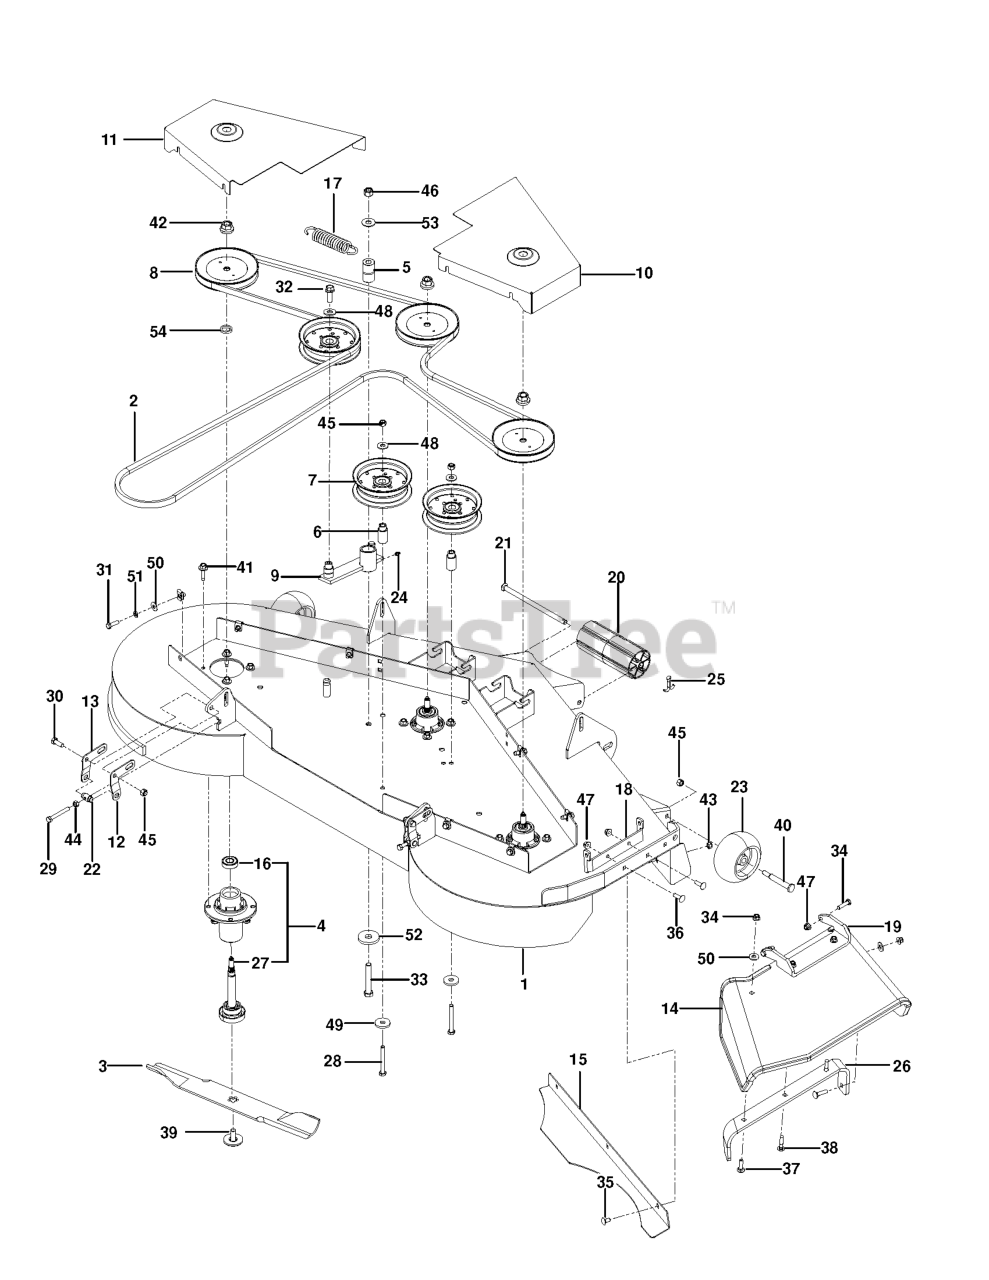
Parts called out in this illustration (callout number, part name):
1	DECK SVC MZT 61 W/DECALS ORG
2	BELT, DECK
3	BLADE, 21"
4	MANDREL ASM, CAST IRON
5	PIVOT BUSHING
6	IDLER BUSHING
7	PULLEY, IDLER
10	BELT SHIELD, RH ORANGE
11	BELT.SHIELD.LH.ORANGE
12	PITCH, ADJUST, RT
13	PITCH, ADJUST, LT
14	CHUTE, RUBBER DISCHARGE 52/61"
15	CONFINEMENT PLATE 61
16	BEARING, BALL
18	BRACKET.M-ZT.CHUTE(ORG)
19	PIVOT BRACKET - CHUTE
20	NOSE ROLLER 48"
21	TRUNION, PITCH
21	ROD.ROLLER.NOSE.NARROW.48"
22	GAUGE WHEEL
23	GAUGE WHEEL
24	ZERK
25	RP_COTTER PIN 1/8 X 3/4
26	BRKT, REINF - CHUTE 52/61"
27	SHAFT ASM MANDREL
28	HCS 3/8C X 3
29	HCS 5/16-18 X 2 1/2 TPBLT
30	HCS 3/8-16X1.GRD.5.ZD
31	HCS 5/16C X 3/4
32	4CS 3/8C X 1 SERRATED HEAD
33	HCS 1/2C X 3 1/4
34	HCS 5/16C X 1 1/4
35	CARRIAGE BOLT 5/16C X 5/8"
36	RHSSNB 5/16C X 1.0
37	BOLT, CARRIAGE 5/16X1-1/4
38	RHSNB 5/16-18 X 1-1/2 GR 5 ZD
39	BOLT.WASHER.ASM.7/16-2
40	SHOULDER BOLT 1/2X2-5/8 ZD SPE
41	WASHER HEAD SCREW
42	LOCKNUT - 9/16
43	NUT 5/16 NYLOC
44	NUT 5/16C HEX
45	NUT 3/8-16 NYLOC
46	NUT 1/2-13 HEX NYLOC ZD
47	5/16-18 NYLOC FLANGE NUT
48	WASHER 3/8 FLAT
49	SPINDLE WASHER
50	WASHER 5/16 FLAT
51	WASH 5/16 DISC SPRING ZD
52	WASHER, SUPPORT
53	WASHER 1/2 FLAT
54	WASHER-SPACER
